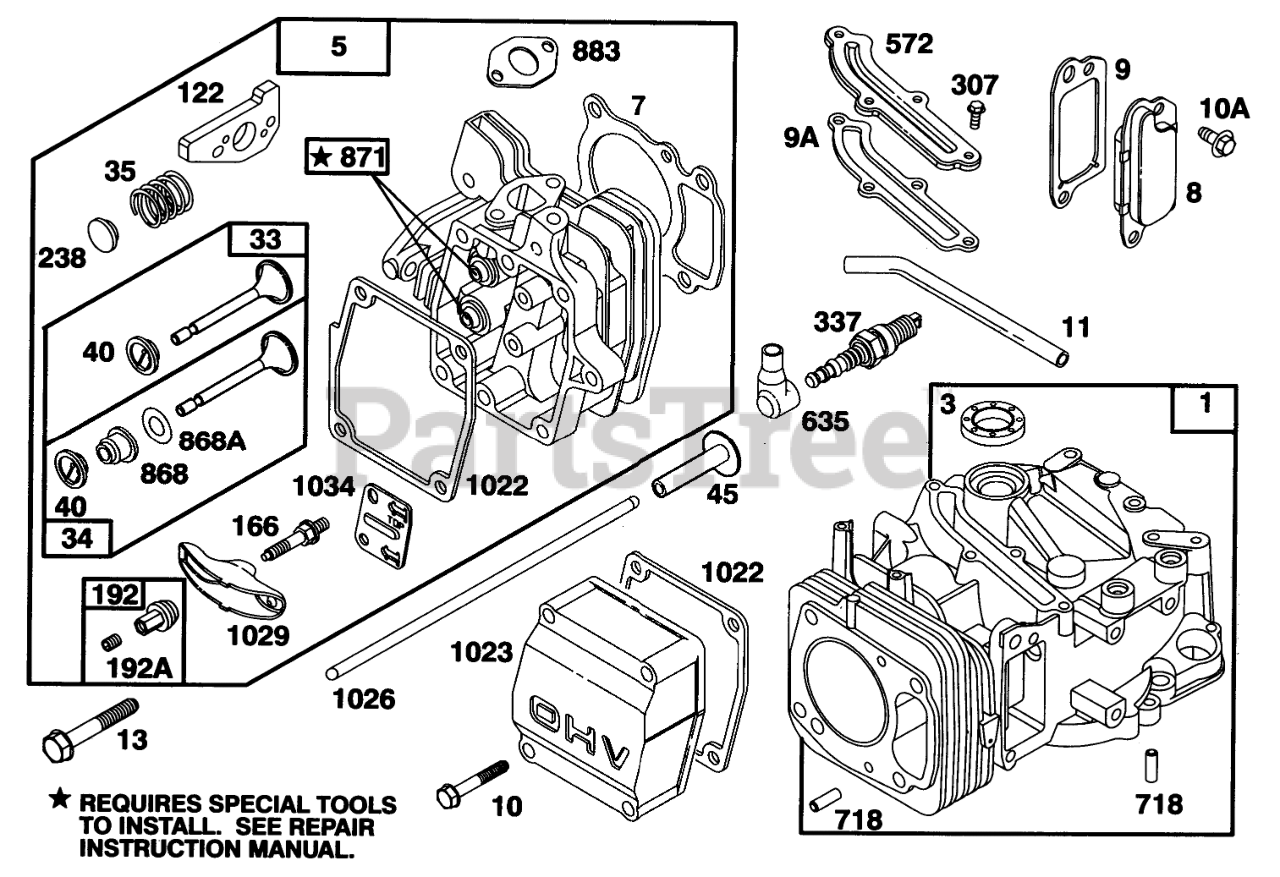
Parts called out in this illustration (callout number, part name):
1	CYLINDER ASSEMBLY
3	SEAL - OIL
5	CYLINDER HEAD
7	CYLINDER HEAD GASKET
8	BREATHER ASM
9	BREATHER GASKET
9A	GASKET-BREATHER
10	HEX HEAD SCREW
10A	HEX HEAD SCREW
11	BREATHER TUBE
13	CYLINDER HEAD SCREW
33	EXHAUST VALVE
34	INTAKE VALVE
35	VALVE SPRING
40	SPRING RETAINER
45	VALVE TAPPET
122	ADAPTER ASSEMBLY
166	ROCKER ARM STUD
192	NUT - HEX SPECIAL
192A	Screw-Set
238	VALVE CAP
307	SCREW - SEM
337	PLUG-SPARK
572	BAFFLE - CYCLINDER
635	SPARK PLUG ELBOW
718	DOWEL - SLEEVE
868	SealAssy-Valve
868A	Seal-Valve
871	Bushing-Guide
883	EXHAUST GASKET
1022	ROCKER COVER GASKET
1023	Cover-Valve
1026	PUSH ROD
1029	ROCKER ARM
1034	PUSH ROD GUIDE
